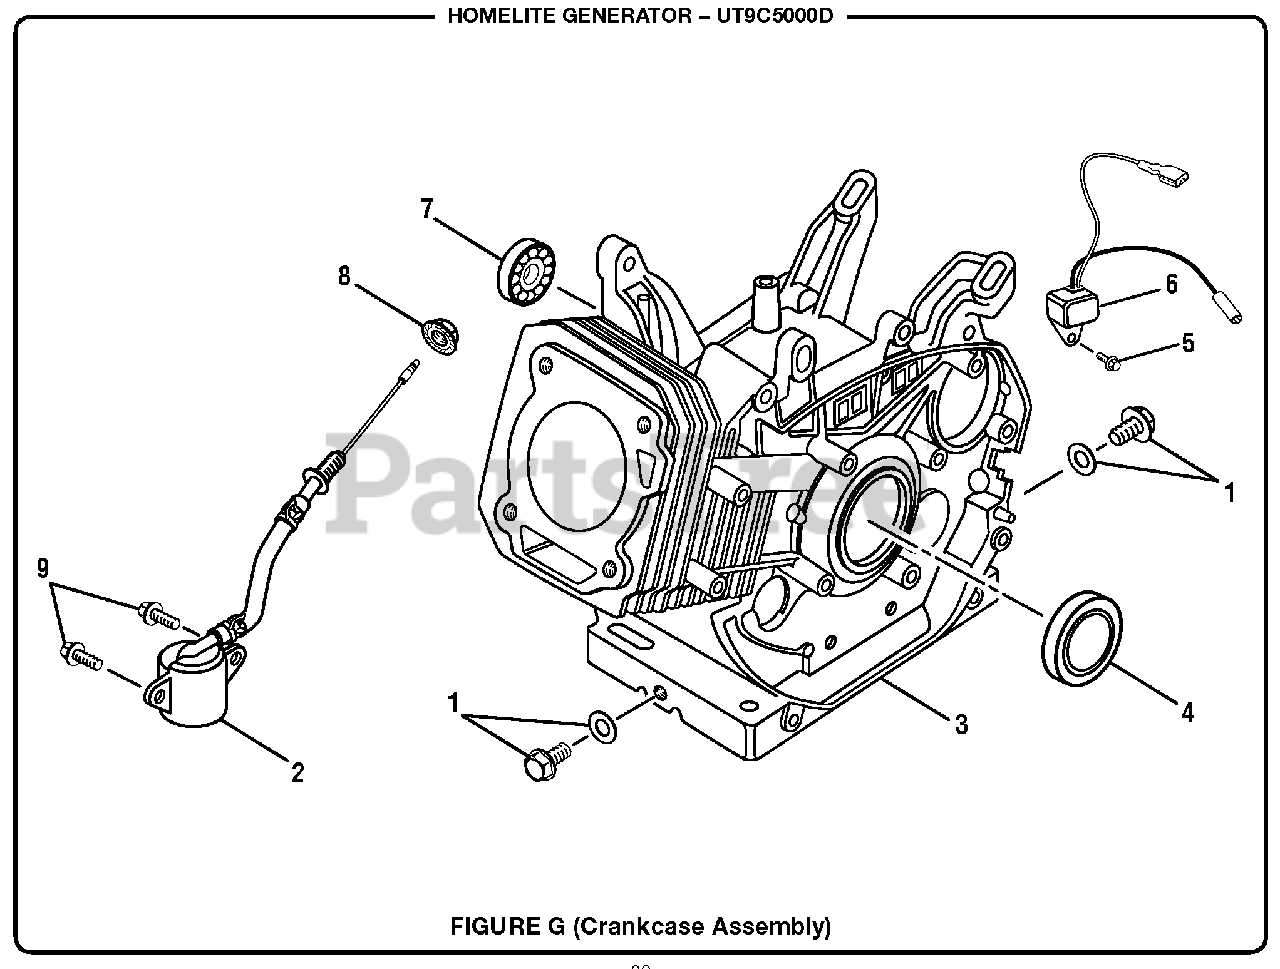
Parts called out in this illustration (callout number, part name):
1	Drain Plug Assembly
2	Oil Sensor Assembly
3	Short Block Cover Assembly w/Crankcase
4	Oil Seal (35 mm x 52 mm x 8 mm)
5	Bolt (M6 x 12 mm Flange Hd)
7	Ball Bearing (6202)
8	Flange Nut (M10)
9	Bolt (M6 x 16 mm, Flange Hd)
